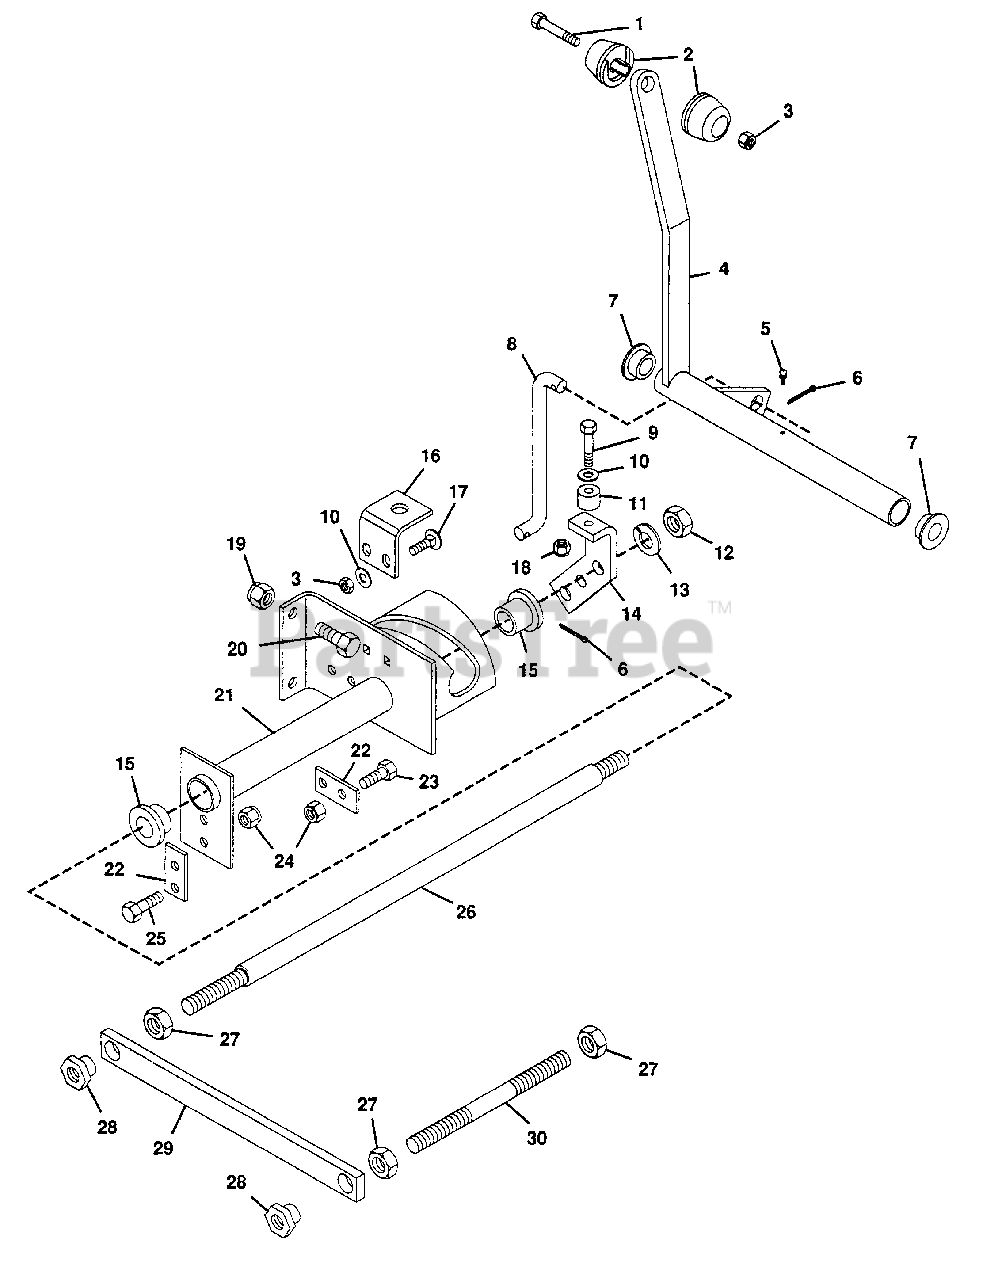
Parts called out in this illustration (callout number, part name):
1	Bolt, Hex 1/4-20x1.50
2	Knob, Control
3	Nut, Lock 1/4-20
4	Control, PTO
5	Fitting, Lube 1/4-28
6	Pin, Cotter .094x1.00
7	Bush., Flg. .515x1.00x.745 Ny.
8	Rod, PTO
9	Bolt, Hex 1/4-28x1.38
10	Washer, Flat .281x.625x.065
11	Roller, Clutch Cam
12	Nut, Hex 1/2-13
13	Washer, Lock 1/2 SP Heavy
14	Arm, PTO Clutch Roller
15	Bush., Flg. .764x1.47x.560 Ny.
16	Bracket, Interlock
17	Bolt, 1/4-20x.75 Rd Hd Sq Nk
18	Nut, Lock 1/4-28
19	Nut, Lock 3/8-16
20	Bolt, Hex 3/8-16x1.00
21	Assembly, PTO Bracket
22	Bracket, Bushing Lock
23	Bolt, Hex 5/16-18x.75
24	Nut, Lock 5/16-18
25	Bolt, Hex 5/16-18x1.00
26	Rod, PTO
27	Nut, Jam 1/2-13 Hex
28	Bush., Flg. .500x.875x.700 Stl.
29	Spring, PTO
30	Stud, PTO
